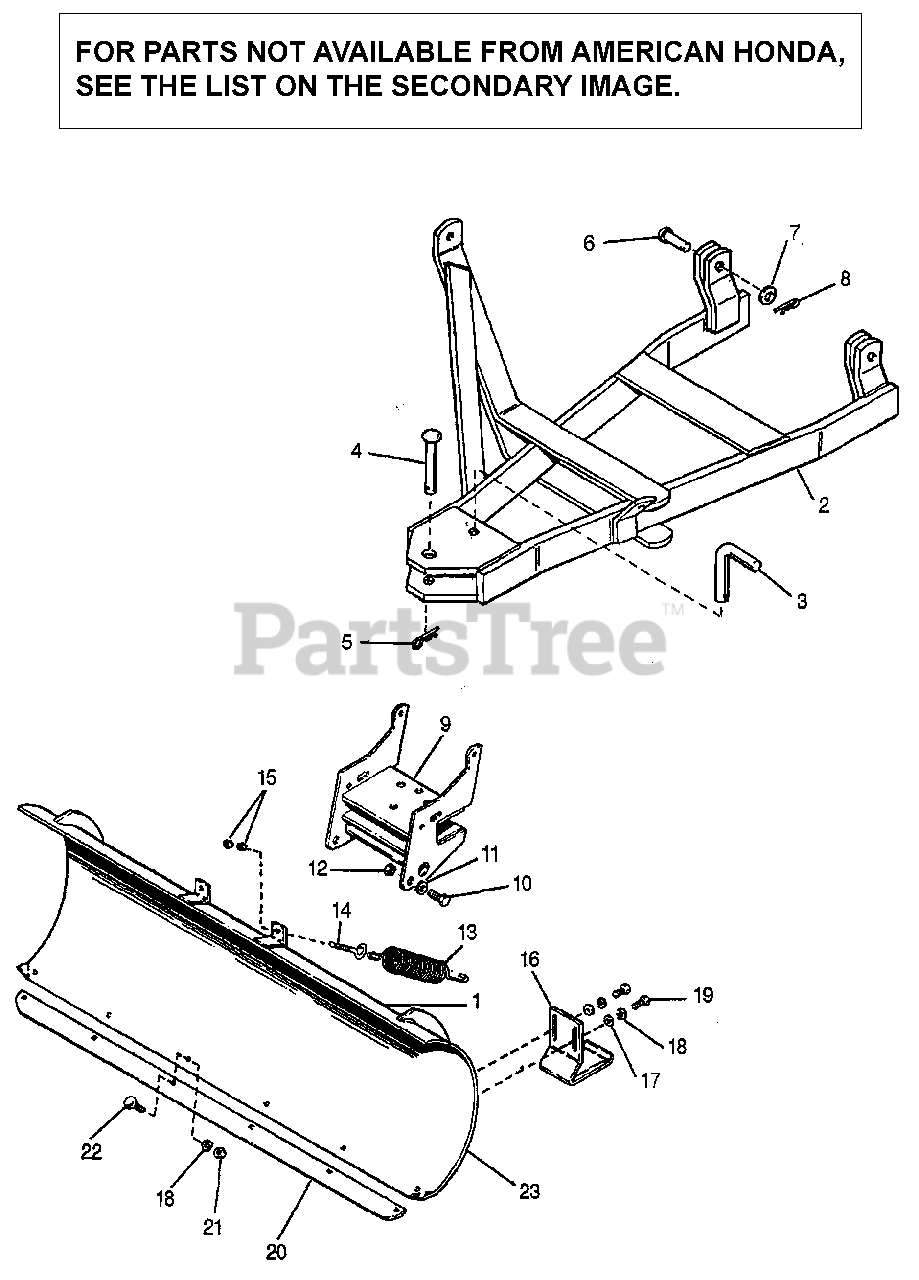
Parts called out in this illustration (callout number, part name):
1	DECAL (NOT AVAILABLE)
3	PIN, PIVOT
5	CLIP, SPRING
6	PIN, CLEVIS
7	WASHER (3/8")
8	PIN, LOCK (10MM)
10	SCREW, CAP (1/2-13X1")
11	SPACER (3/4")
12	NUT, LOCK HEX. (1/2-13)
13	SPRING, TENSION
14	BOLT, EYE
15	NUT, HEX. (5/16-18) (NOT AVAILABLE)
16	SHOE, SKID
17	WASHER (3/8")
18	WASHER, LOCK (0.375)
19	SCREW, CAP (3/8-16X3/4")
20	PLATE, WEAR
21	NUT, HEX. (3/8-16)
22	BOLT (3/8-16X1)
